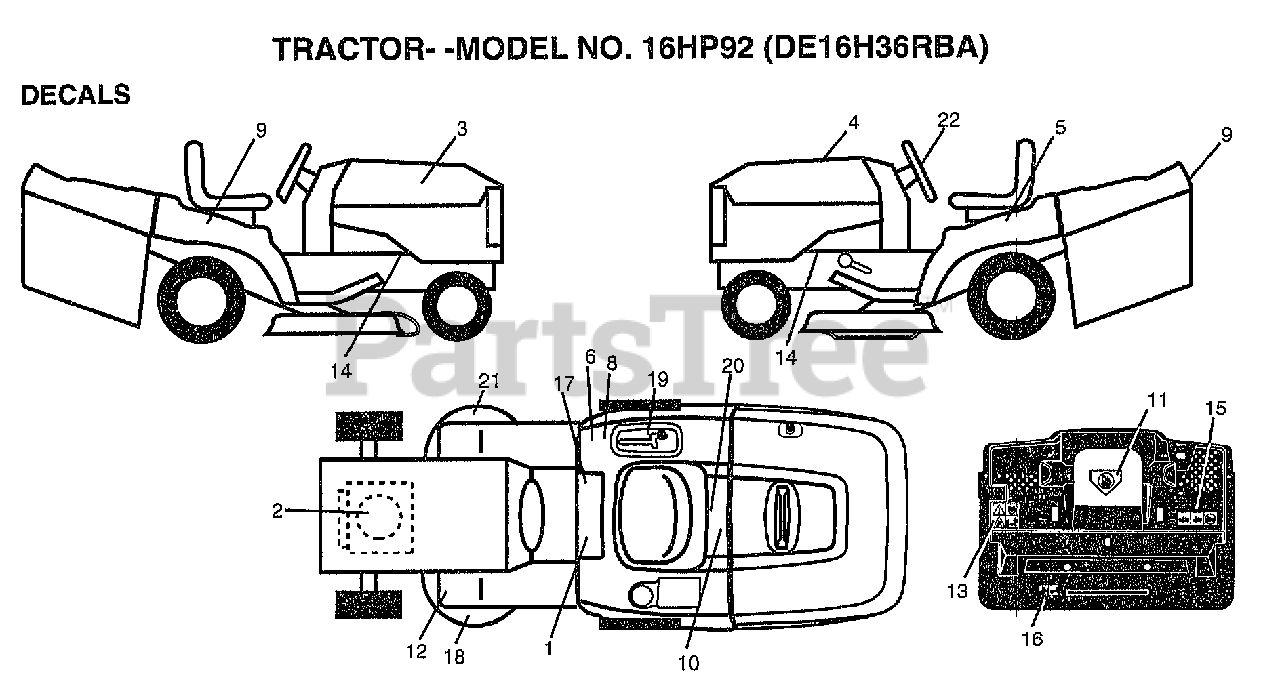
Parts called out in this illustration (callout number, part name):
1	DECAL.READ.O.MANU
2	DECAL, ENGINE
4	DECAL HOOD
5	DECAL.FENDER.LOGO
8	DECAL.EURO.ST.CE.
9	DECAL.FENDER.LOGO
10	DECAL.BATRY.3-3908
11	DECAL.DANGER.CUTF
12	DECAL-BRAKE/CLUTC
13	DECAL.WARNING.BACKPLATE.CRD
14	"DECAL CHASSIS,HOT"
15	DECAL, OPER BAG
16	DECAL.DRAWBAR.LDL
17	DECAL BRAK PARK
18	DECAL.DECK.MOWER
19	DECAL.CONSOLE.HDYRO.CRD
20	DECAL.BYPASS.FENDER.CRD.LT.YT
21	DECAL.DECK.HEX.BELT
22	DECAL.INST.STEERING
